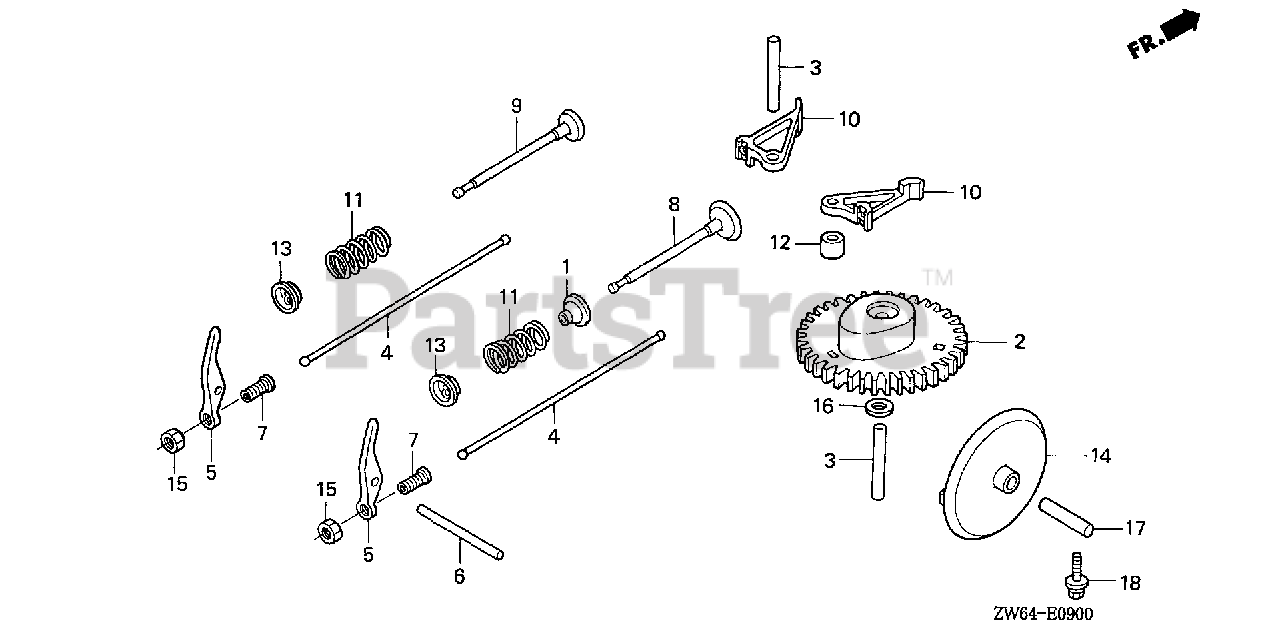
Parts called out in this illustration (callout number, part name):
1	SEAL, VALVE STEM
3	PIN, OIL PUMP
3	ROLLER (5X29.8)
5	ARM, VALVE ROCKER
6	ROLLER (4X37.8)
7	PIVOT, ROCKER ARM
8	VALVE, IN.
9	VALVE, EX.
10	LIFTER, VALVE
11	SPRING, VALVE
12	COLLAR, LIFTER
13	RETAINER, VALVE SPRING
14	SLINGER, OIL
15	NUT, TAPPET ADJUSTING
16	WASHER (6MM)
17	ROLLER (6X25)
18	BOLT-WASHER (5X16)
